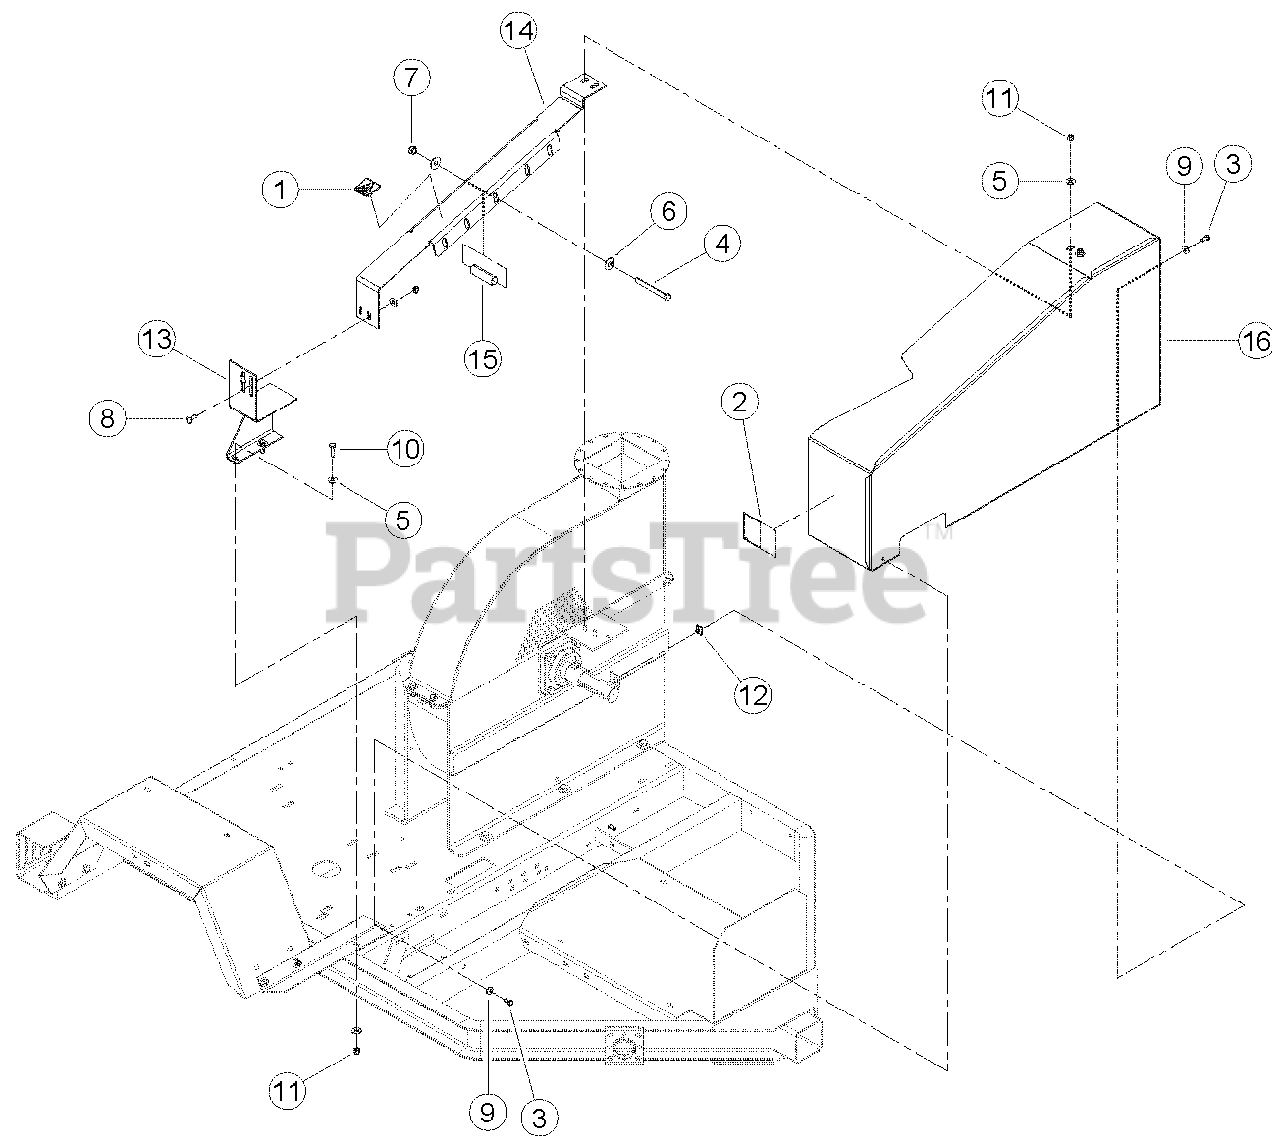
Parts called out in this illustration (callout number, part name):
1	DECAL, SHIELD DANGER ISO
2	DECAL, CLUTCH ENGAGEMENT ISO
3	BOLT, 5/16 X 3/4 HEX HD GR5 ZP
4	BOLT, 1/2 X 4-1/2 HHCS GR5 NC ZP
5	WASHER, 3/8 FLAT ZP
6	WASHER, 1/2 FLAT ZP
7	NUT, 1/2 CENTERLOCK GRB ZP
8	BOLT, 3/8 X 1 CRG GR5 ZP
9	WASHER, 5/16 FLAT ZP
10	BOLT, 3/8 X 1-1/4 HEX HD GR5 ZP
11	NUT, 3/8 NE NYLOCK ZP
12	NUT, 5/16-18 TINNERMAN U-TYPE
13	WELDMENT, BELT GUIDE
14	SPACER, 1.0 X 3-1/8
15	SHIELD, BELT
16	WELDMENT, 50 HP BELT GUARD
